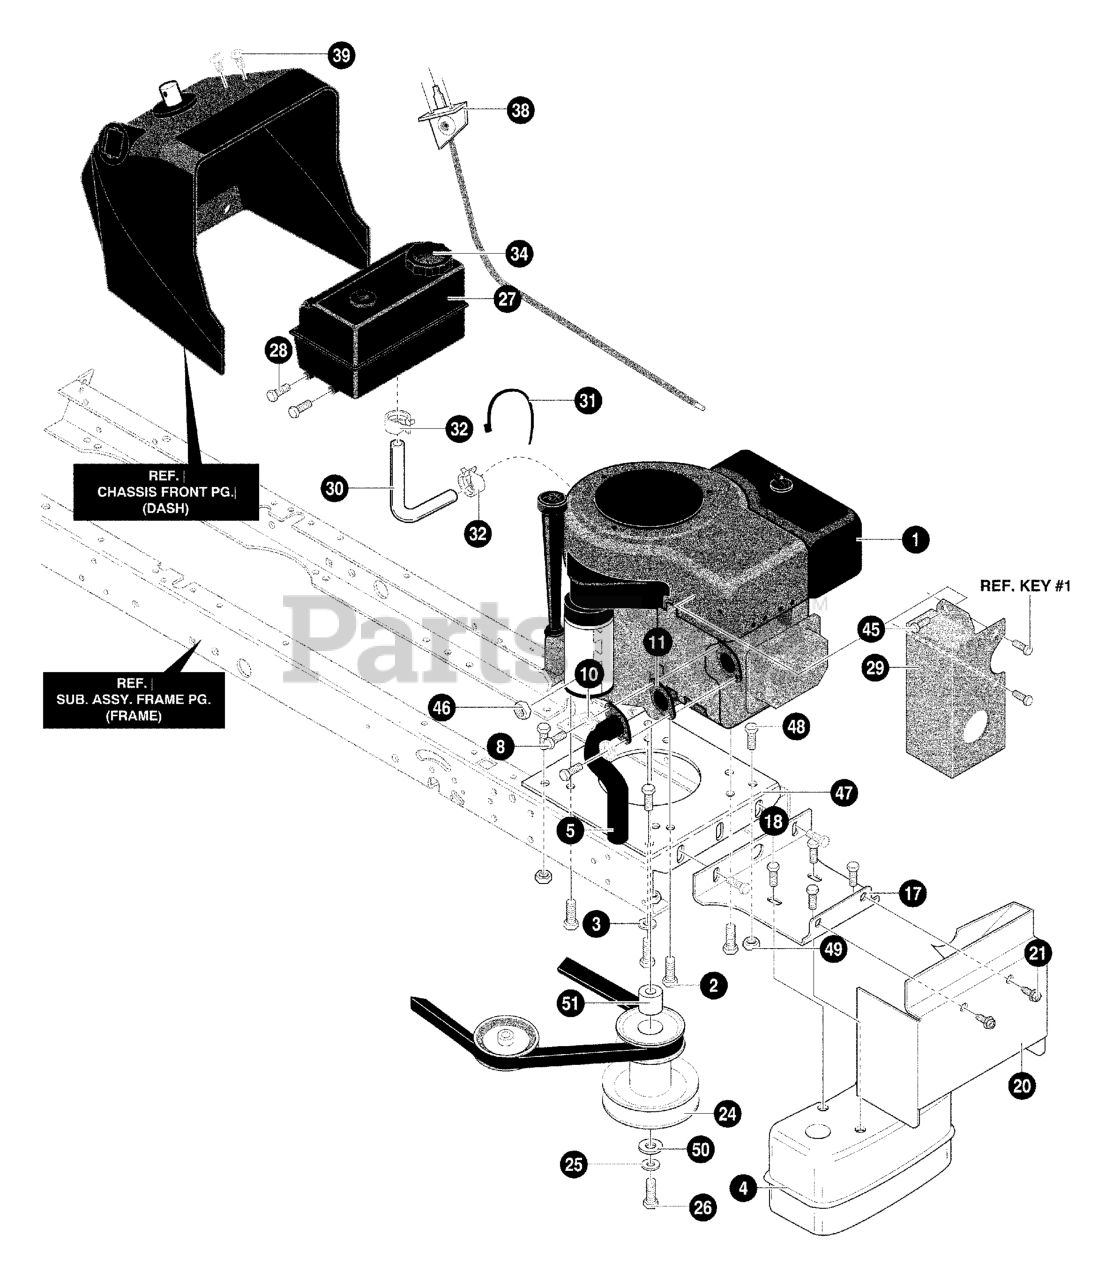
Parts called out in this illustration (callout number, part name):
1	Engine *
2	SCREW, 3/8- 16X1.25
4	MUFFLER
5	EXHAUST TUBE
8	SCREW, 5/16-18 x 0.75
10	WASHER
11	GASKET, Exhaust
17	BRACKET, MUFFLER MOUNT
18	SCREW, 1/4-20X .75
20	SHIELD, HEAT
21	SCREW, 5/16-18 x 0.75
24	PULLEY, STACK
26	SCREW, 7/16-20
27	TANK, FUEL
29	HEAT SHIELD
30	Fuel Line (Must cut to length)
31	TIE, CABLE
32	CLAMP, HOSE
34	CAP, FUEL
38	THROTTLE CONTROL
39	SCREW, 10- 24X.63
45	SCREW, 10- 16X .50
46	NUT, 1/4- 20
47	PLATE, ENGINE
48	SCREW, 5/16-18 x 0.75
49	NUT, 5/16- 18
50	WASHER, FLAT
